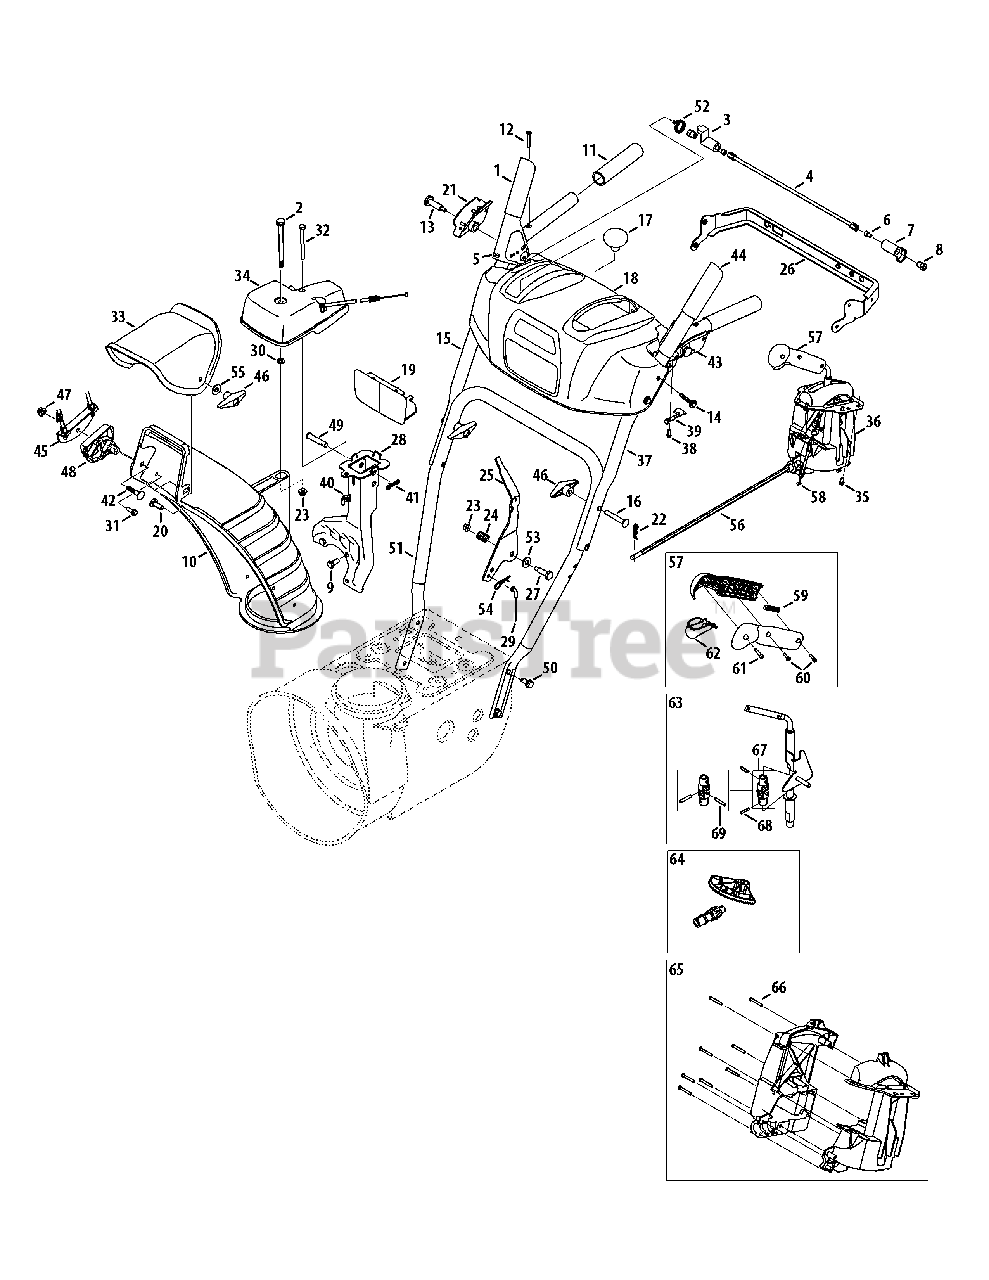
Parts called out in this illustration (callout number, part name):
1	Handle Engagement Ass’y RH
2	Flange Shoulder Screw
3	Lock Plate
4	Pivot Rod
5	Rubber Bumper
6	Screw, 1/4-20 x .500
7	Clutch Lock Cam
8	Shoulder Nut, 1/4-20
9	Hex Screw, 5/16-24 x .750
10	Lower Chute
11	Handle Grip
12	Screw, #10-24 x 0.375
13	Shoulder Screw, 1/4-20
14	Screw, 1/4-20 x 1.625
15	Upper Handle RH
16	Carriage Screw, 5/16-18 x 2.25
17	Shift Knob
18	Handle Panel
20	Carriage Bolt, 5/16-18 x 1.0
21	Handle Clutch Lock RH Assy
22	Cotter Pin
23	Flange Lock Nut, 1/4-20
24	Compression Spring
25	Shift Lever
26	Panel Bracket
27	Shoulder Screw
28	Chute Support Bracket
29	Speed Selector Cable
30	Flat Washer, .25 x .630 x .0515
31	Hi-Lo Screw, 1/4-15 x .75
32	Hex Screw, 1/4-20 x 3.00
33	Upper Chute
34	4-Way Chute Gearbox Assembly
35	Hi-Lo Screw, 1/4-15 x 0.5
36	4-Way Chute Control™ Assembly
37	Upper Handle LH
38	Screw, #8-16 x 0.50
39	Clutch Lock Spring
40	Wing Nut, 1/4-20
41	Bow Tie Cotter Pin
42	Carriage Bolt, 5/16-18 x 1.50
43	Handle Clutch Lock LH Assy
44	Handle Engagement Assembly LH
45	Cable Bracket
46	Wing Knob
47	Flange Lock Nut, 5/16-18
48	Chute Tilt Cable Guide
49	Clevis Pin
50	Screw, 5/16-18 x 0.75
51	Lower Handle
52	Torsion Spring
53	Flat Washer
54	Click Pin
55	Flat Washer, .349 x .879 x .063
56	Chute Rod
57	Handle Assembly
58	4-Way Cable
59	Handle Plunger
60	Screw, Mach., #8-32 x .750
61	Screw, #8 x 1.00
62	Handle Lever
63	Shift Assembly
64	Gear Set Assembly
65	Handle Housing Assembly
66	Screw, #8-18 x 1.250
67	Joint Block Assembly
69	Roll Pin
